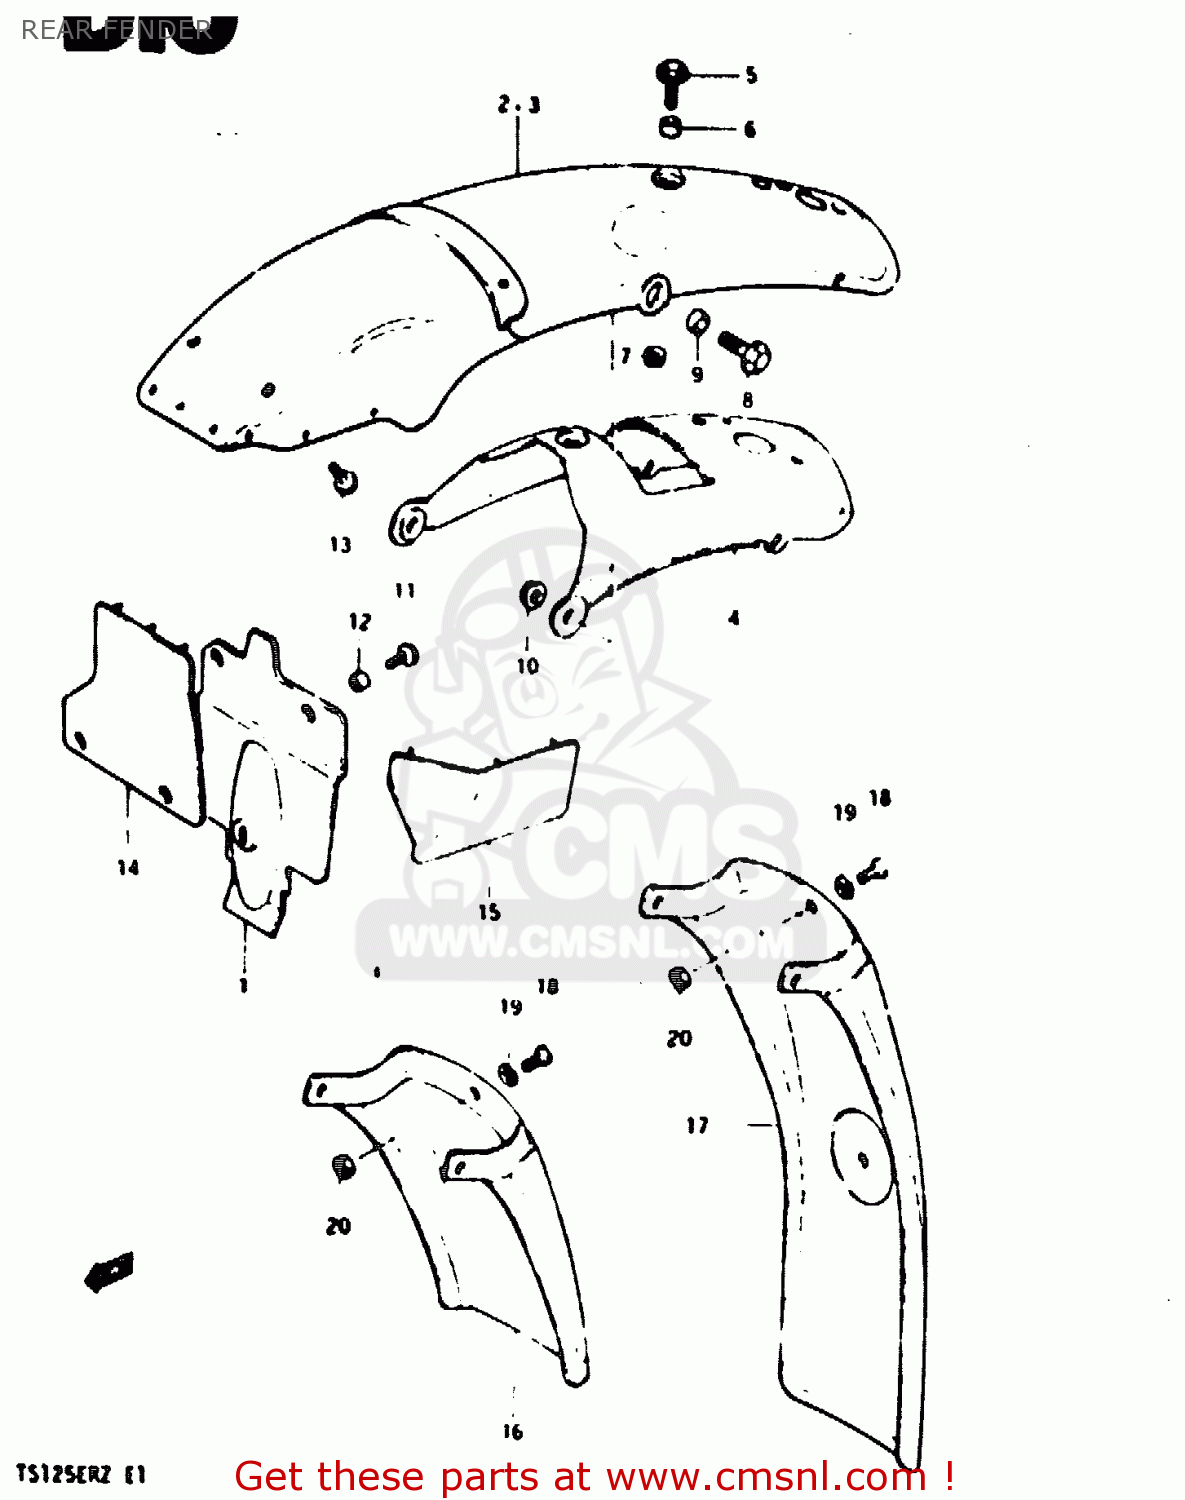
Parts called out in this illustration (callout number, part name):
1	REAR FENDER, FRONT
2	FENDER, REAR (RED)
4	REINFORCEMENT,REAR FENDER
5	BOLT,REAR
6	SPACER
7	NUT
8	BOLT
9	SPACER(8.2X14X4.5)
10	NUT
11	SCREW, FRONT
12	SPACER
13	SCREW
14	MUD FLAP, FRONT
15	MUDGUARD,RR FENDER FR,L
